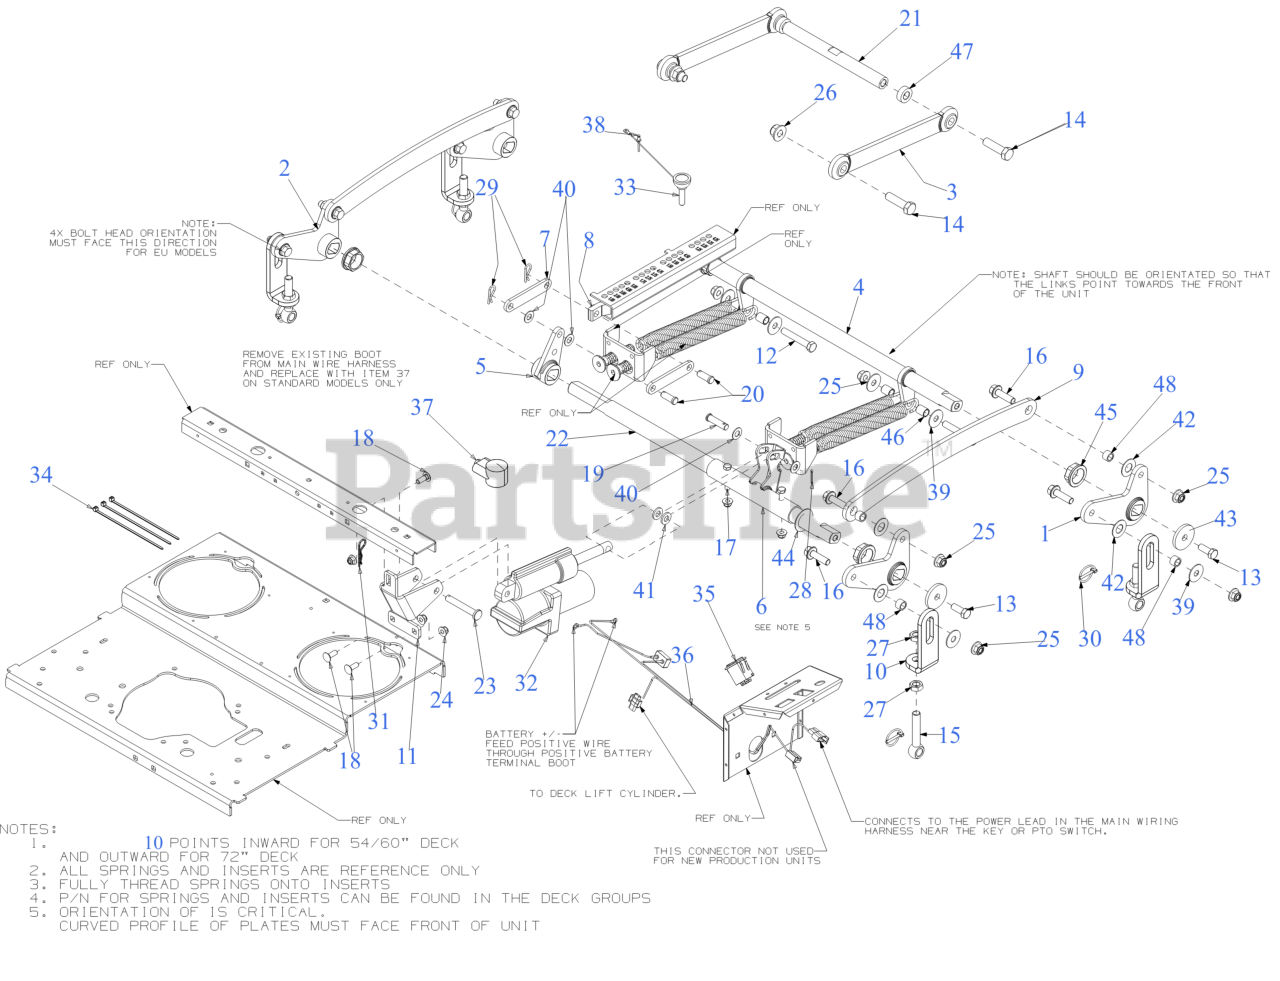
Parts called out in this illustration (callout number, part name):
4	FRONT DECK LIFT SHAFT
5	DECK LIFT HUB ASSEMBLY (LH)
6	LIFT BRACKET
7	DECK LIFT INDEX LINK
8	LIFT INDEX SLIDER ARM
11	LIFT CYLINDER BRACKET
12	SCREW-HEX 1/2-13 x 3.00
13	SCREW 1/2-13 x 1.25 GR5
14	SCREW 5/8-11 x 2.25 GR5
15	EYE BOLT 5/8-11 x 3.63
16	FLANGE BOLT 1/2-13:1.75:GR5
17	SCREW 3/8-16 x 2.0 GR 8
18	CARRIAGE BOLT 3/8-16 x 1.00 GR5
19	CLEVIS PIN .500 x 1.875
20	CLEVIS PIN .500 x 1.25
21	FRONT LIFT SHAFT
22	LIFT SHAFT 1.25 DIA
23	CLEVIS PIN .50"OD
26	FLANGE LOCK NUT
28	COTTER PIN-1/8 D
29	COTTER PIN
30	LYNCH PIN .1875
31	COTTER PIN .125X2.
32	ELEC/HYD LIFT CYLINDER
33	DECK LIFT KNOB
34	7" CABLE TIE
35	DECK LIFT SWITCH
36	ELECTRIC DECK LIFT WIRING HARNESS
37	BATTERY BOOT
38	FULL TUBULAR RIVET
39	WASHER .51 x 1.5 x .07
40	FLAT WASHER .510 x .995
41	FLAT WASHER .510 x 1.000 x .125
42	FLAT WASHER
43	FLAT WASHER .53"x2.125"x.25"
44	THRUST WASHER 1.25X1.94X.063 7000
45	FLANGE BEARING
46	SPACER 0.535 x 0.68 x 0.83
47	SPACER .635X1.25X.445
